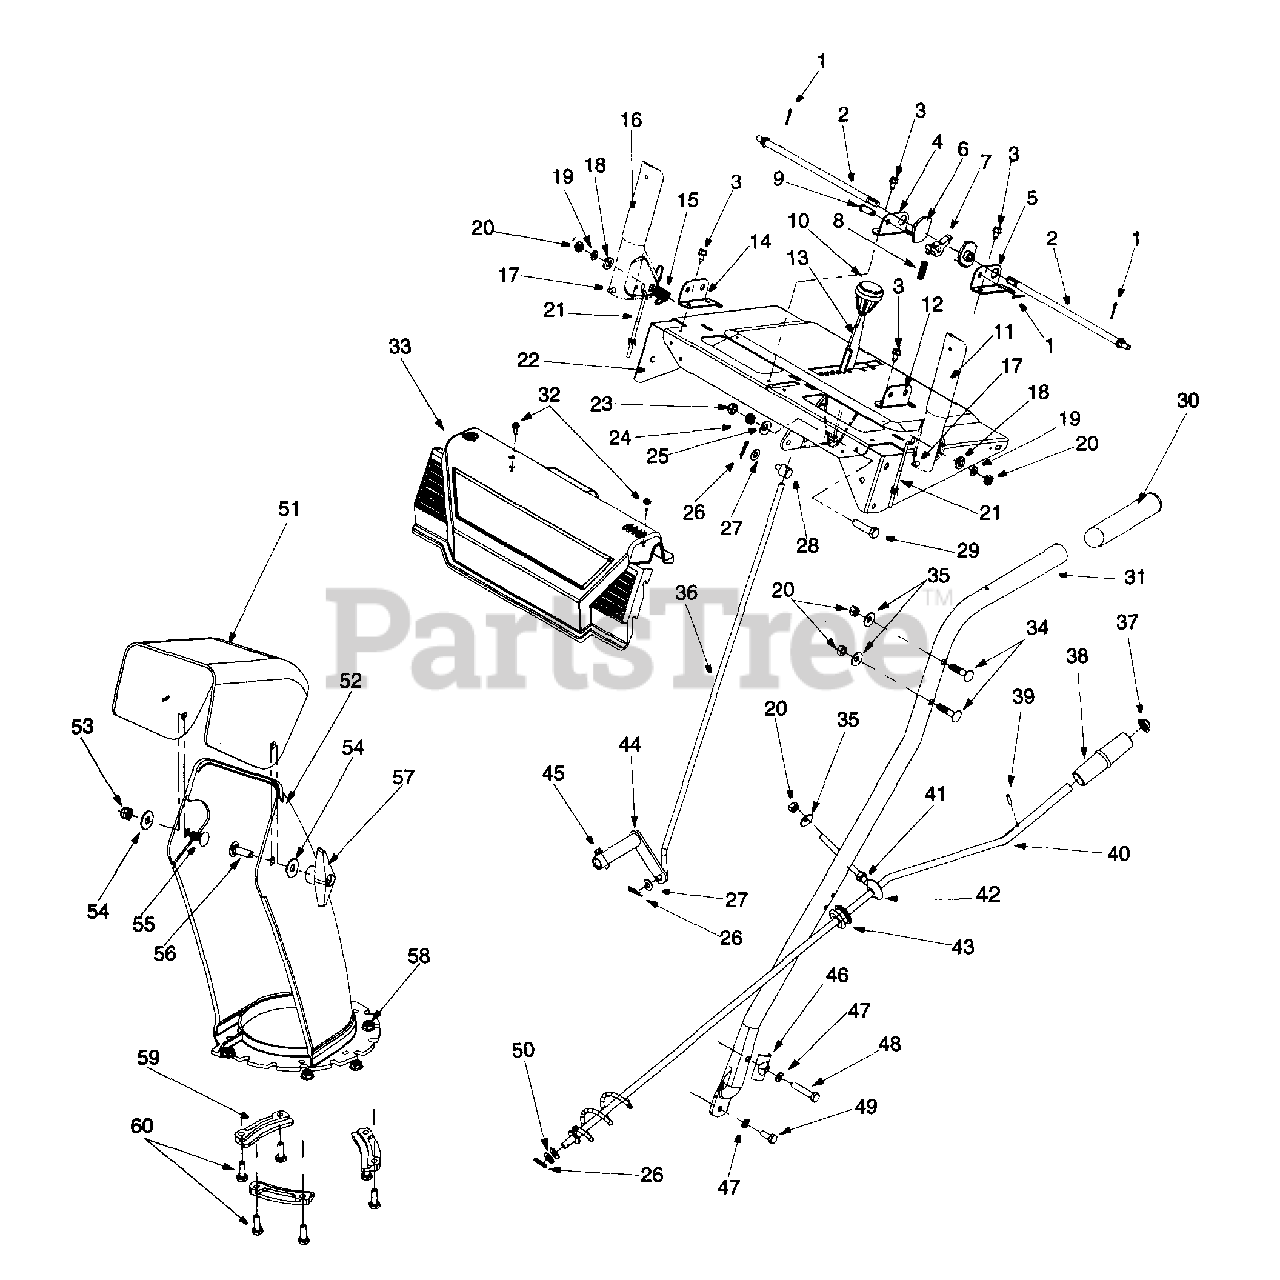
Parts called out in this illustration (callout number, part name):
1	Cotter Pin
3	Hex Washer Screw 1/4-20 x .5
4	Handle Support Bracket - RH
5	Handle Support Bracket - LH
6	Cam Lock Handle
7	Handle Lock Pawl
8	Compression Spring
9	Clevis Pin
11	Handle Assy - LH
13	Shift Handle
14	Handle Support Bracket - RH
15	Torsion Spring
16	Handle Assy - RH
17	Rubber Bumper
18	Washer
19	Lock Washer 5/16
20	Hex Nut 5/16-18
21	Cable
24	Compression Spring
25	Bell Washer
26	Cotter Pin
27	Flat Washer 5/16
28	Ferrule
29	Hex Cap Screw 3/8-24 x 1.50
31	Handle - RH
31	Handle - LH
32	Hew Washer Screw
33	Handle Panel
33	Handle Panel w/Top Light
34	Carriage Bolt 5/16-18 x 1.50
35	Bell Washer .340 ID x .872 OD
36	Shift Rod
37	Push Cap
38	Chute Knob
39	Roll Pin
40	Chute Crank
41	Hex Nut 5/16 - 18
42	Chute Crank Eyebolt
43	Rubber Grommet
44	Shift Arm Assembly
45	Hex Washer Screw 1/4-20 x 1.0
46	Handle Tab
47	Lock Washer 5/16
48	Hex Cap Screw 5/16-18 x 1.75
49	Hex Cap Screw 5/16-18 x .75
50	Flat Washer
51	Upper Chute
52	Lower Chute
53	Hex Lock Nut 5/16-18
54	5/16 Washer
55	Carriage Bolt 5/16-18 x .75
56	Carriage Screw 5/16-18 x 1.0
57	Knob
58	Hex Lock Nut 1/4-20
59	Flange Keeper
60	Hex Cap Screw 1/4-20 x .75
